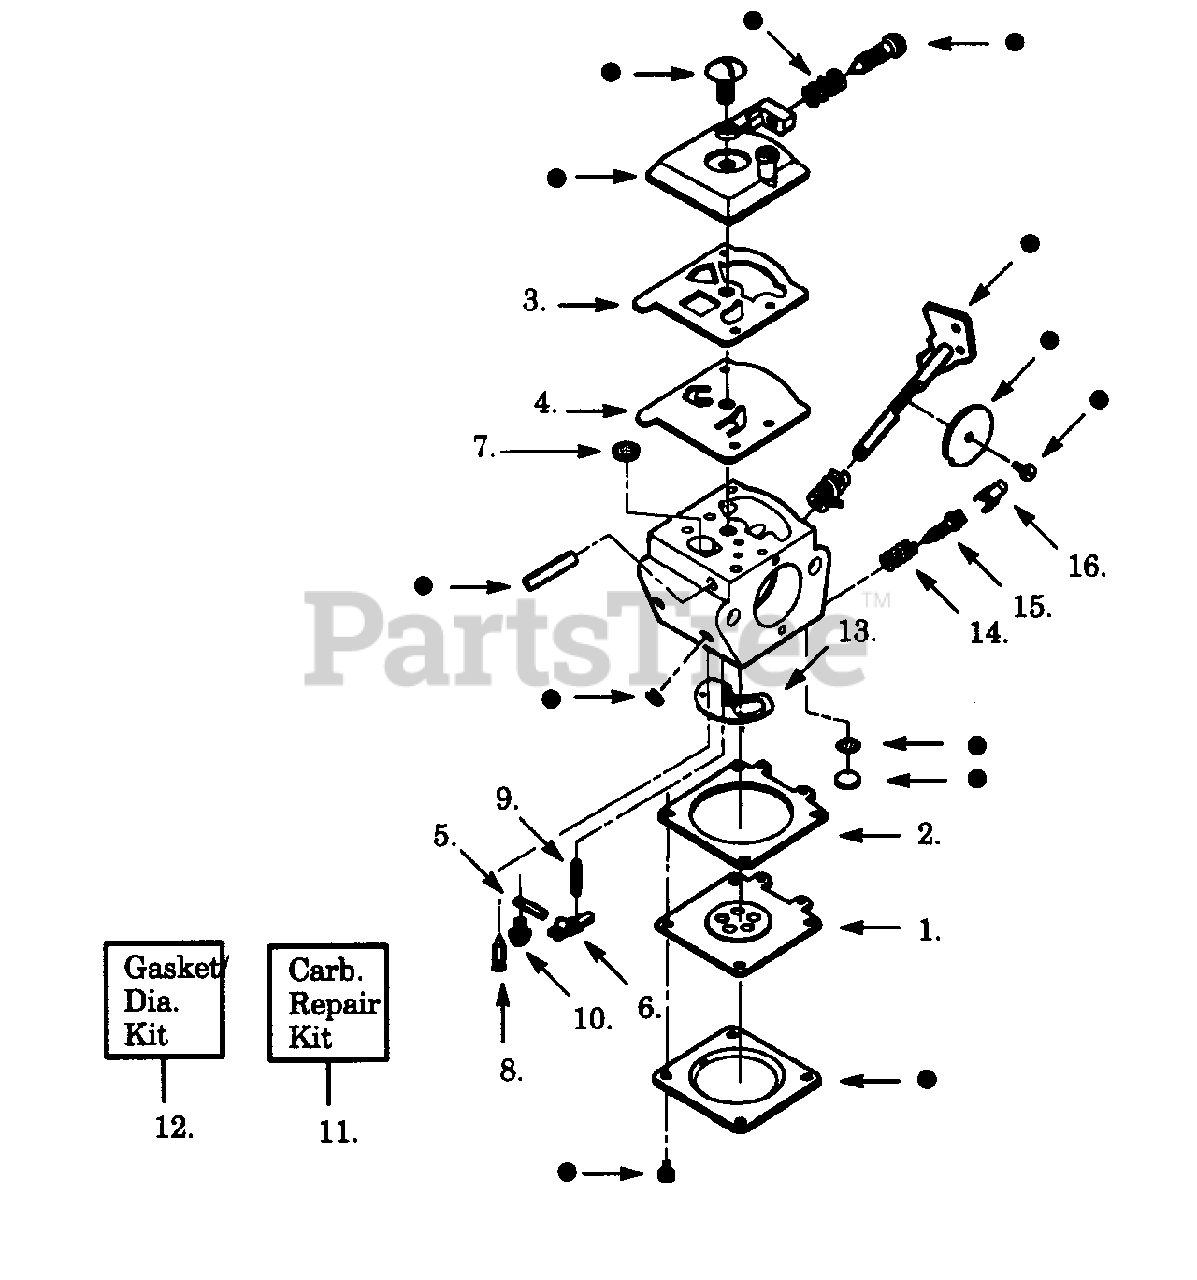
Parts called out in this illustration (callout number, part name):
1	Metering Diaphragm
2	Metering Diaphragm Gasket
3	Pump Gasket
4	Pump Diaphragm
5	Metering Lever Pin
6	Metering Lever
7	Fuel Inlet Screen
8	Inlet Needle Valve
9	Metering Lever Spring
10	Metering Lever Pin Screw
11	Carburetor Repair Kit
12	Gasket/Diaphragm Kit
13	Circuit Plate Gasket
14	Spring-Idle Needle-Type II
15	Idle Needle-Type II
16	Limiter Cap-Type II
